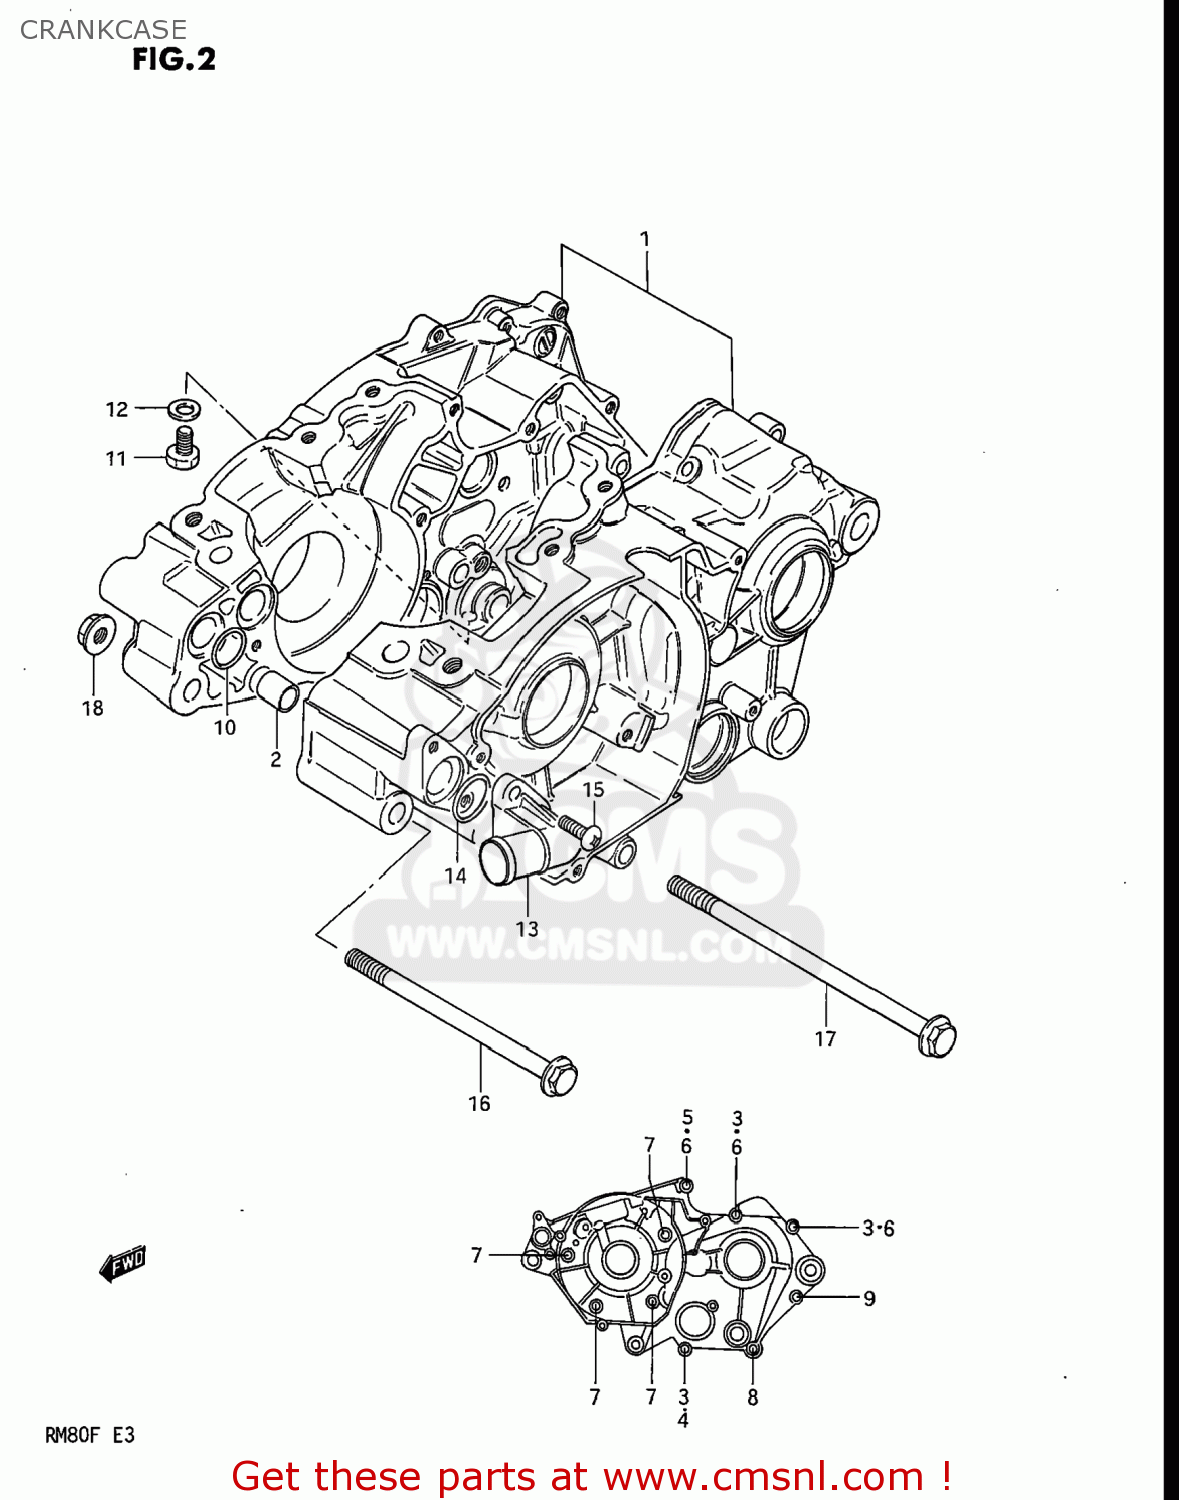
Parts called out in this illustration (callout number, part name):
1	CRANKCASE SET
2	PIN
3	SCREW
4	SCREW
5	SCREW (6X35)
6	SCREW (6X35)
7	SCREW
8	SCREW (6X45)
9	SCREW
10	O-RING,BOSS
11	BOLT
12	GASKET 8.2X14X1 (NAS)
13	CONNECTOR,WATER HOSE
14	O-RING,BOSS
15	SCREW
16	BOLT(8X95)
17	BOLT(8X125)
18	NUT
